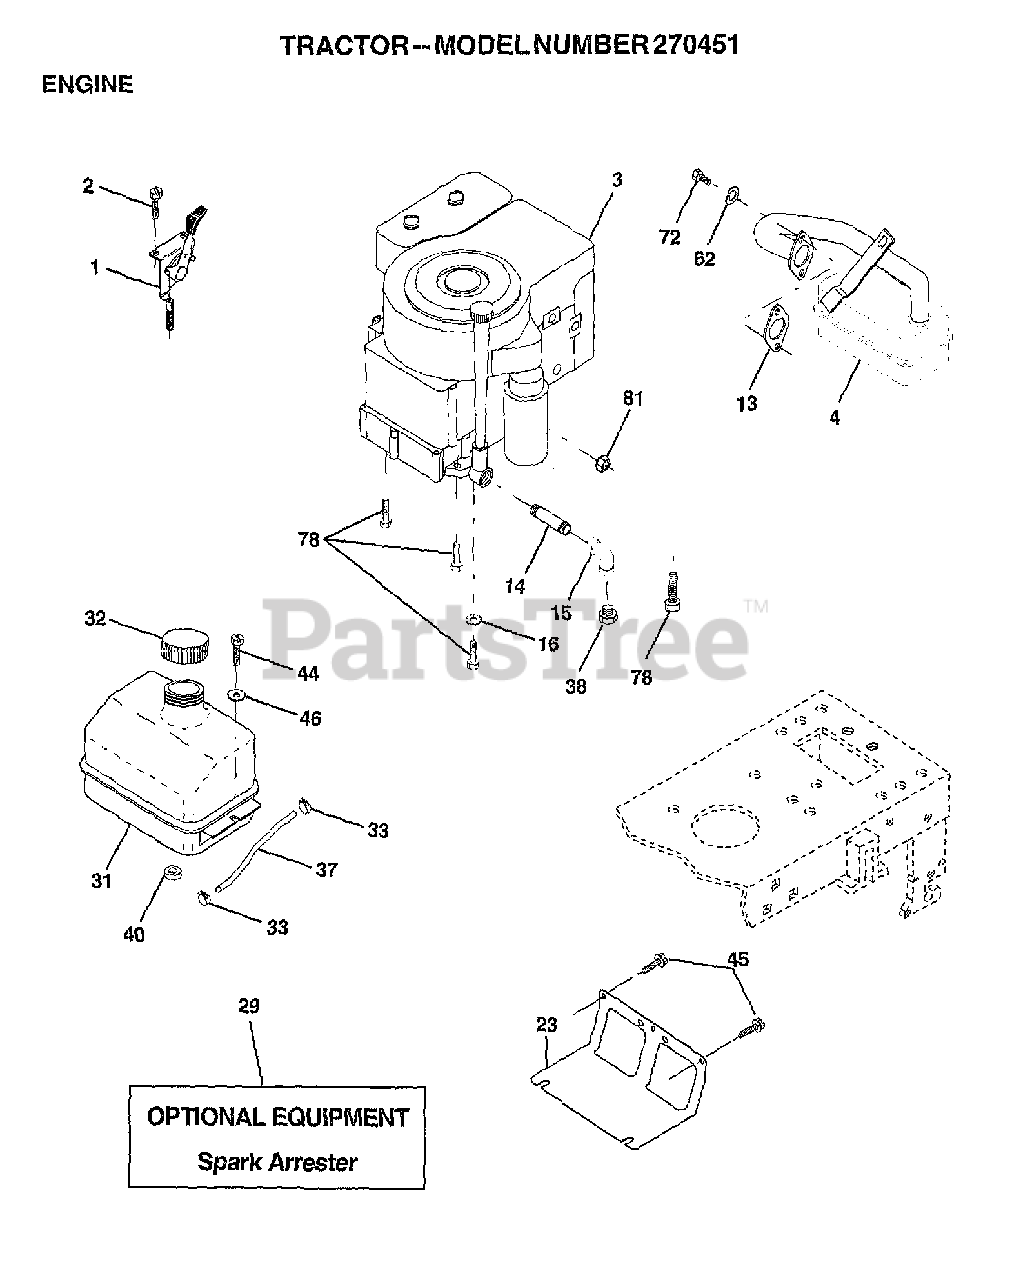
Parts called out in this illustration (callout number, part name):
1	CONTROL THROTTLE
2	SCREW LT
4	MUFFLER
14	PIPE NIPPLE
15	ELBOW
16	LOCKWASHER
23	SHIELD BROWNING
31	TANK.FUEL.LT.
32	CAP ASM FUEL
33	HOSE CLAMP
37	LINE FUEL
44	SCREW
45	SCREW
46	WASHER
62	LOCKWASHER
72	SCREW
78	SCREW
81	NUT
